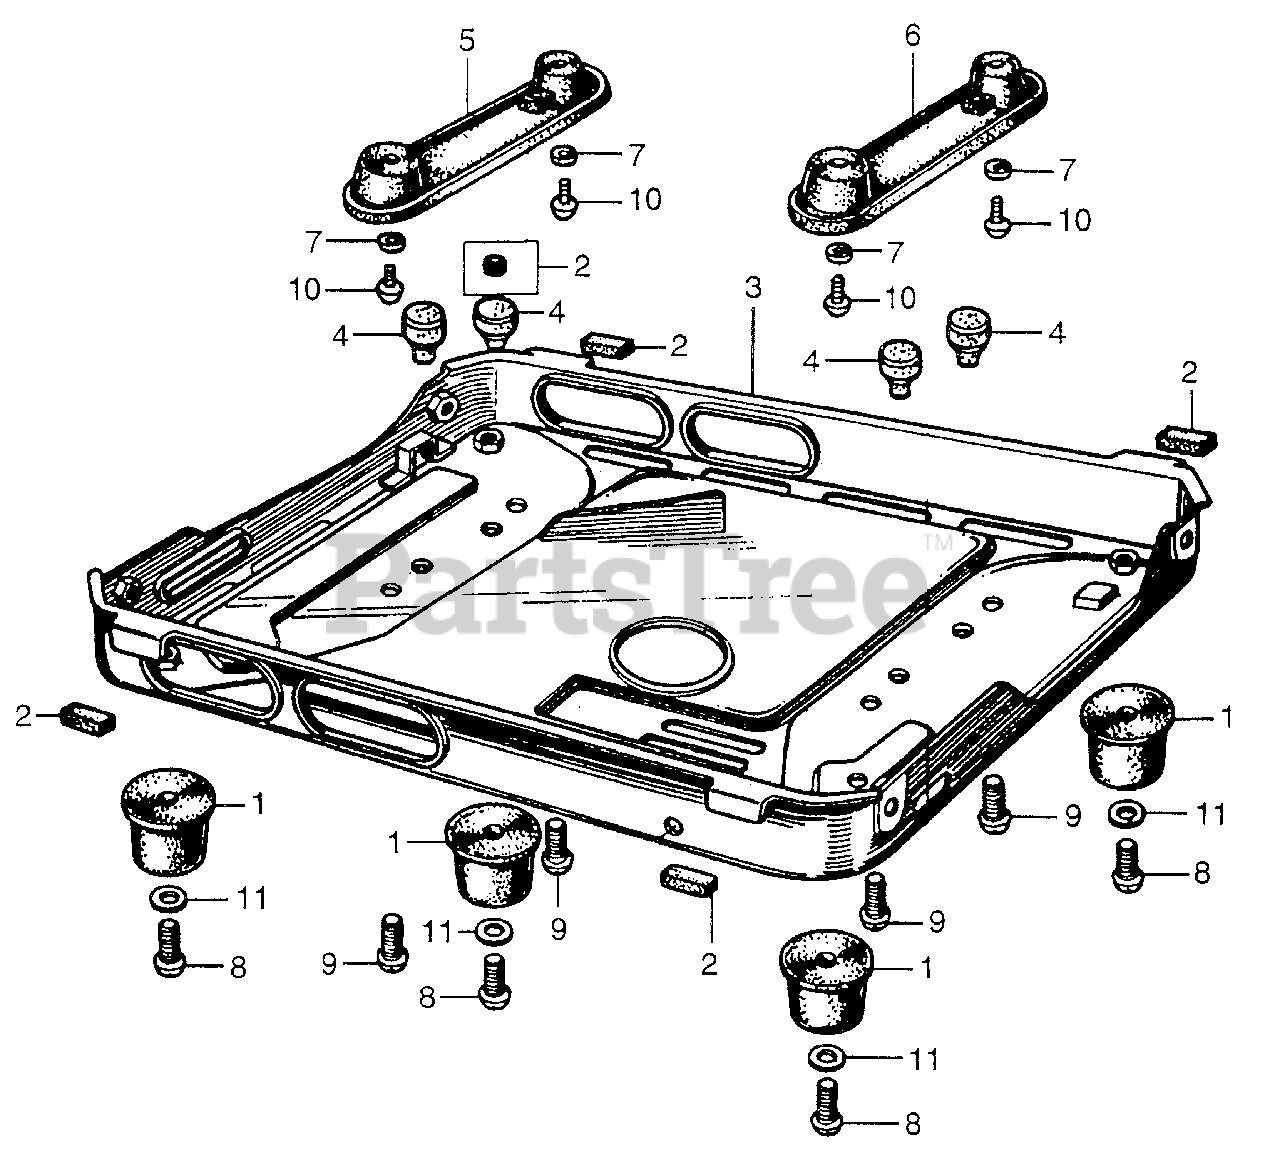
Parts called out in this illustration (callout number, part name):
1	RUBBER (LOWER)
2	RUBBER, GUIDE (NOT AVAILABLE)
3	COVER (LOWER)
3	COVER (LOWER) *NH1* (BLACK) (NOT AVAILABLE)
4	RUBBER, SETTING STOPPER (NOT AVAILABLE)
5	FRAME, ENGINE (NOT AVAILABLE)
6	FRAME, ALTERNATOR (NOT AVAILABLE)
7	WASHER (6MM)
8	SCREW, PAN (5X10)
9	SCREW, PAN (5X10)
10	SCREW, PAN (5X12)
11	WASHER, SPRING (5MM)
